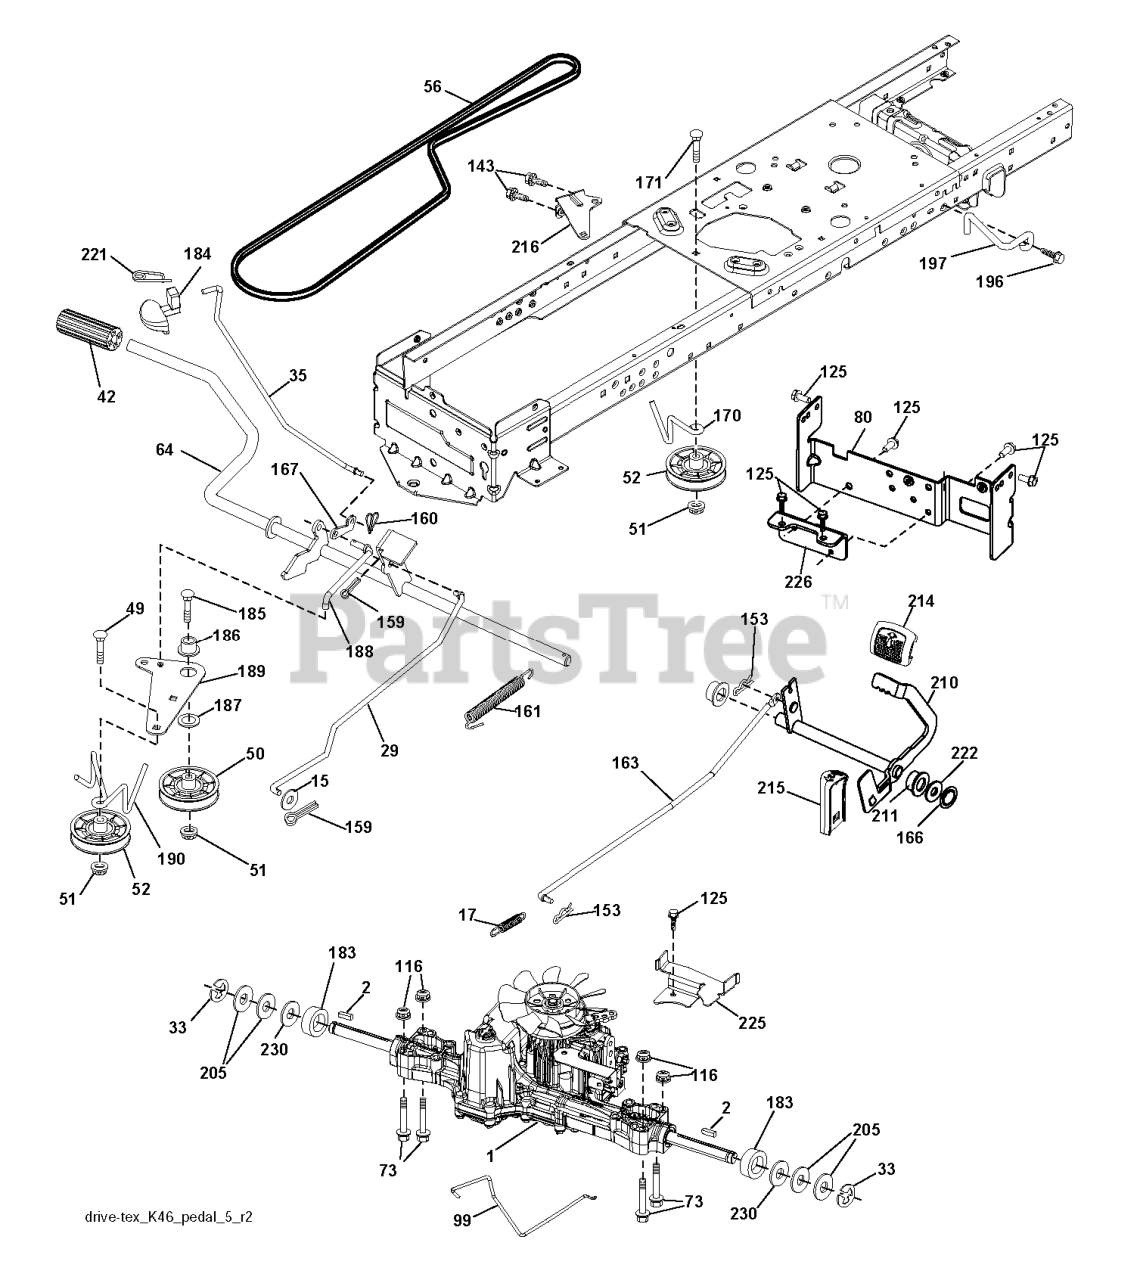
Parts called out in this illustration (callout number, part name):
2	SQUARE KEY
15	WASHER
17	SPRING.BRAKE.K46.GREEN
29	ROD.BRAKE.K46
35	ROD.CNTRL.PARK.PREDATOR.LT.TEX
42	PEDAL COVER T
50	IDLER.FLAT.910.OFFSET
51	NUT LOCK FLG 3/8-16 UNC
52	IDLER.V-GROOVE.910.OFFSET
56	V-BELT.MOWER.92.40.42/K46
64	SHAFT.ASM.PEDAL.BRK.CNTR
73	BOLT HEX 5/16-18 GR 5
80	STRAP TORQUE
99	ROD.SPRING.BYPASS.K46.LT.Z
116	NUT LOCK HEX FLANGE 5/16-18
125	SCREW
143	Screw 5/16-18 x 1/2 Hex, Self Tapping 5/16-18 x 1/2
153	RETAINER M
159	COTTER PIN
160	RETAINER CLIP
161	SPRING, RETURN LT
163	ROD.CONTROL.PEDAL.K46
166	NUT.PUSH.625.2006
167	LATCH.BRAKE.SPRING
169	BOLT HEX 5/16-18 GR 5
170	KEEPER.V-IDLER.CENTER.
171	BOLT
183	SPACER AXLE
184	HANDLE PARKING BRAKE
186	SPACER.RETAINER
187	WASHER 12/32X2X10GA
188	RP.LINK.CLUTCH.GROUND.DRIVE
189	BELLCRANK.GROUND.DRIVE.TEX.
190	KEEPER.BELLCRANK.DRIVE
196	SCREW 3/8-16X1
197	LINK.CLUTCH.ANIT-ROTAT
210	ROCKER.ASM.PEDAL.CONTR
211	BEARING.NYLON
214	PEDAL.FORWARD.TEX.GT.4
215	PEDAL.REVERSE.TEX.GT.4
216	BRACKET.PULLEY.IDLER.W/TEX
221	RETAINER.SPRING.CLIP.H
222	WASHER 21/32 X 1-1/4 X 10 GA.
225	KEEPER.BELT.TRANSAXLE.K46
226	BRACKET.MOUNT.TORQUE.K46.TLT
230	WASHER.HARDENED
